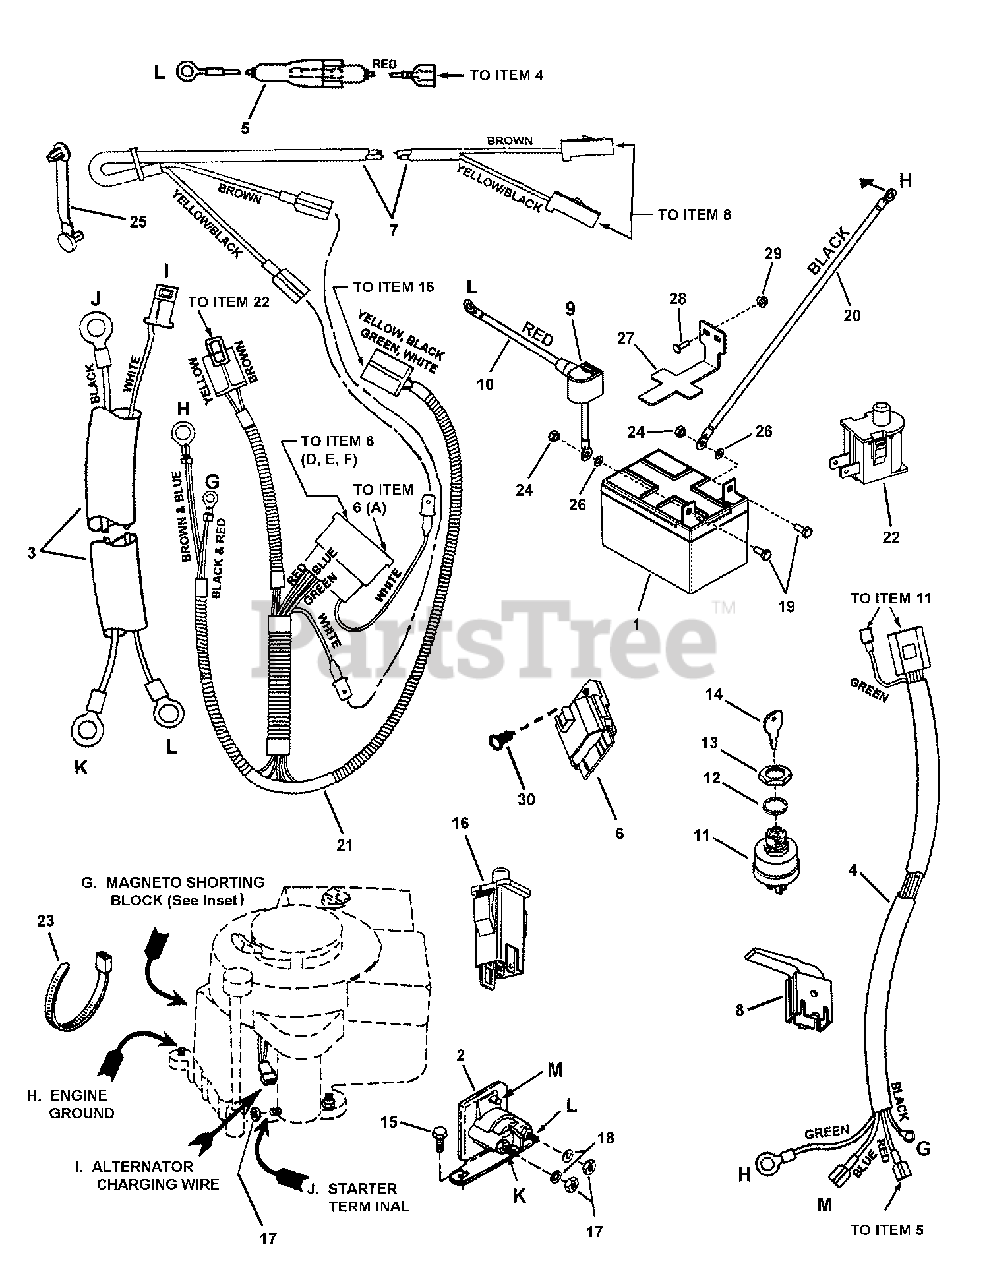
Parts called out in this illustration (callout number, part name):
1	BATTERY KIT, 12V 20HR: 190CCA
2	SOLENOID, Super Trombetta, RER
3	WIRE HARNESS, Starter
4	WIRE HARNESS, M Series, Electric Start
5	HOLDER, Fuse
6	INTERLOCK MODULE, Briggs
7	HARNESS, (Deck Interlock Wiring)
8	SWITCH, Deck Interlock (NO)
9	BOOT, Insulator
10	WIRE, Positive, 17" Long
11	SWITCH, Ignition, 4 Terminal, Indak
12	WASHER, 5/8" Internal Tooth Lock
13	NUT, 5/8-32 Hex
14	KEYS, BLISTER PK KIDS+MWRS DON'T MIX,DOM
15	SCREW, 1/4-20 x 1/2" Hex Washer Self-Tap
16	SWITCH, Operator Presence Control (OPC) Traction (NC/NO)
17	NUT, 1/4-20 Hex, GR 5 or B
18	WASHER, 1/4" Internal Tooth Lock
19	SCREW, 1/4-20 x 5/8 Hex Head Cap, GR 5, YZ
20	WIRE, Negative, 15" Long, Black
21	HARNESS, Operator Presence Control (OPC) Wire
22	SWITCH, Seat (NC)
23	CABLE TIE, 7"
24	NUT, 1/4-20 Hex Center Lock, GR 5 or B
25	CABLE TIE, 3.19" long
26	RETAINER, 1/4" Bolt, BP
27	BRACKET, Battery, RER
28	BOLT, #10-24 x 3/4, Round Head Square Neck Carriage, YZ
29	NUT, #10-24 Hex Flange Lock, BZ
30	FASTENER, 1/4" Ratchet
